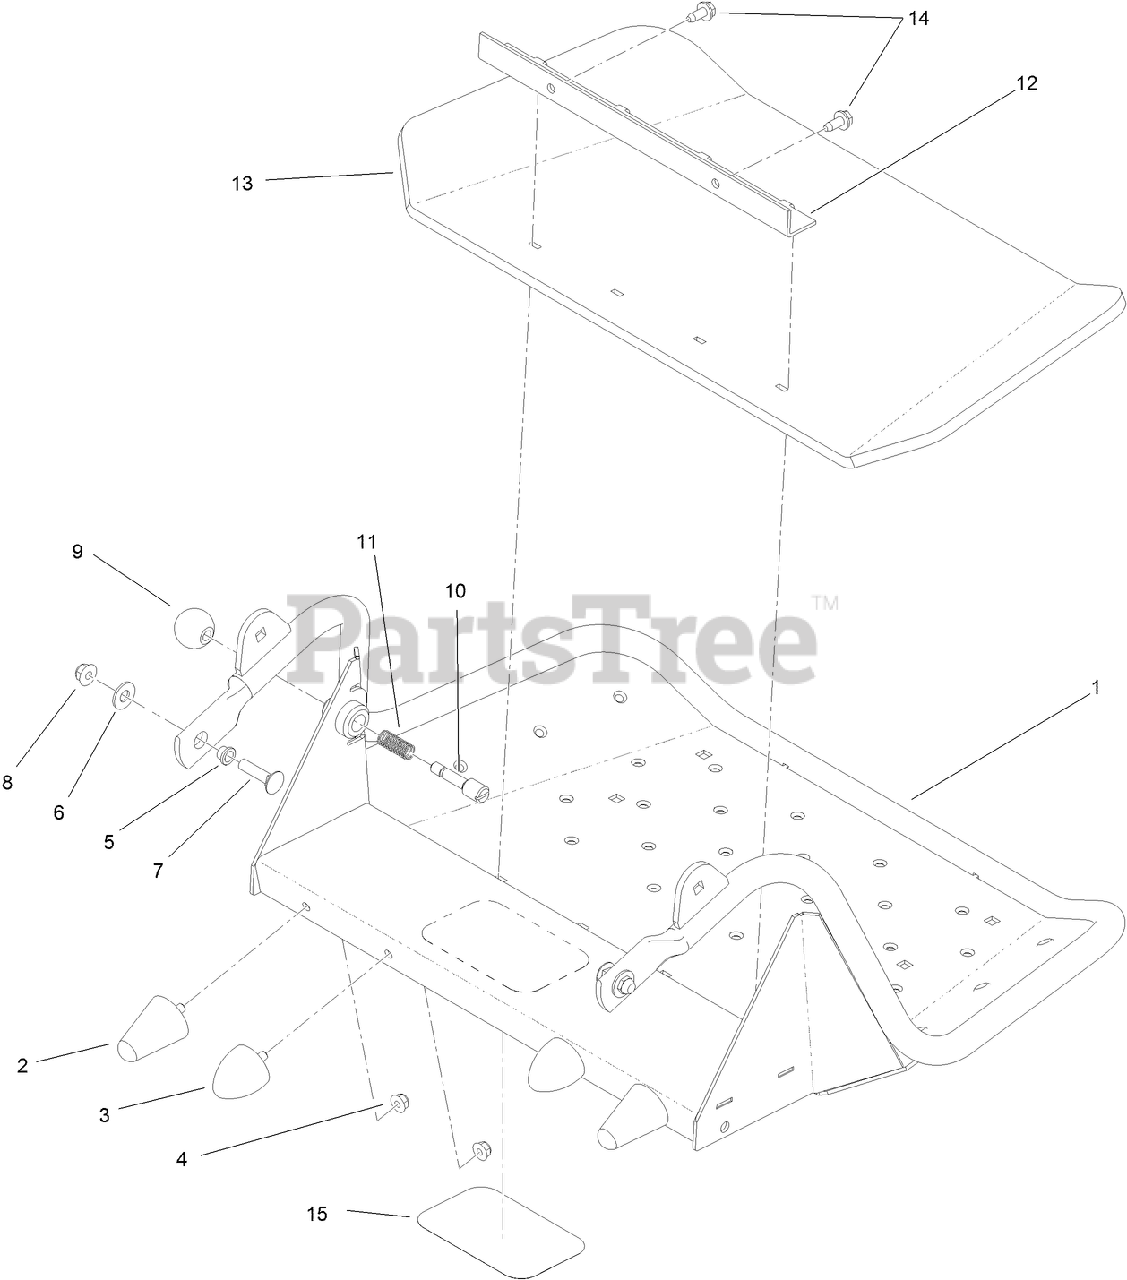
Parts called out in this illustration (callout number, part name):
1	PLATFORM
2	BUMPER-RUBBER
3	BUMPER-RUBBER
4	NUT-HF, NI
5	BUSHING-FLANGED
6	WASHER-FLAT
7	SCREW-CARR
8	NUT-HF, NI
9	KNOB-BALL
10	PIN-LATCH
11	SPRING
12	CLAMP-SHIELD
13	MAT-FOOT
14	SCREW-HWHTF
15	DECAL
